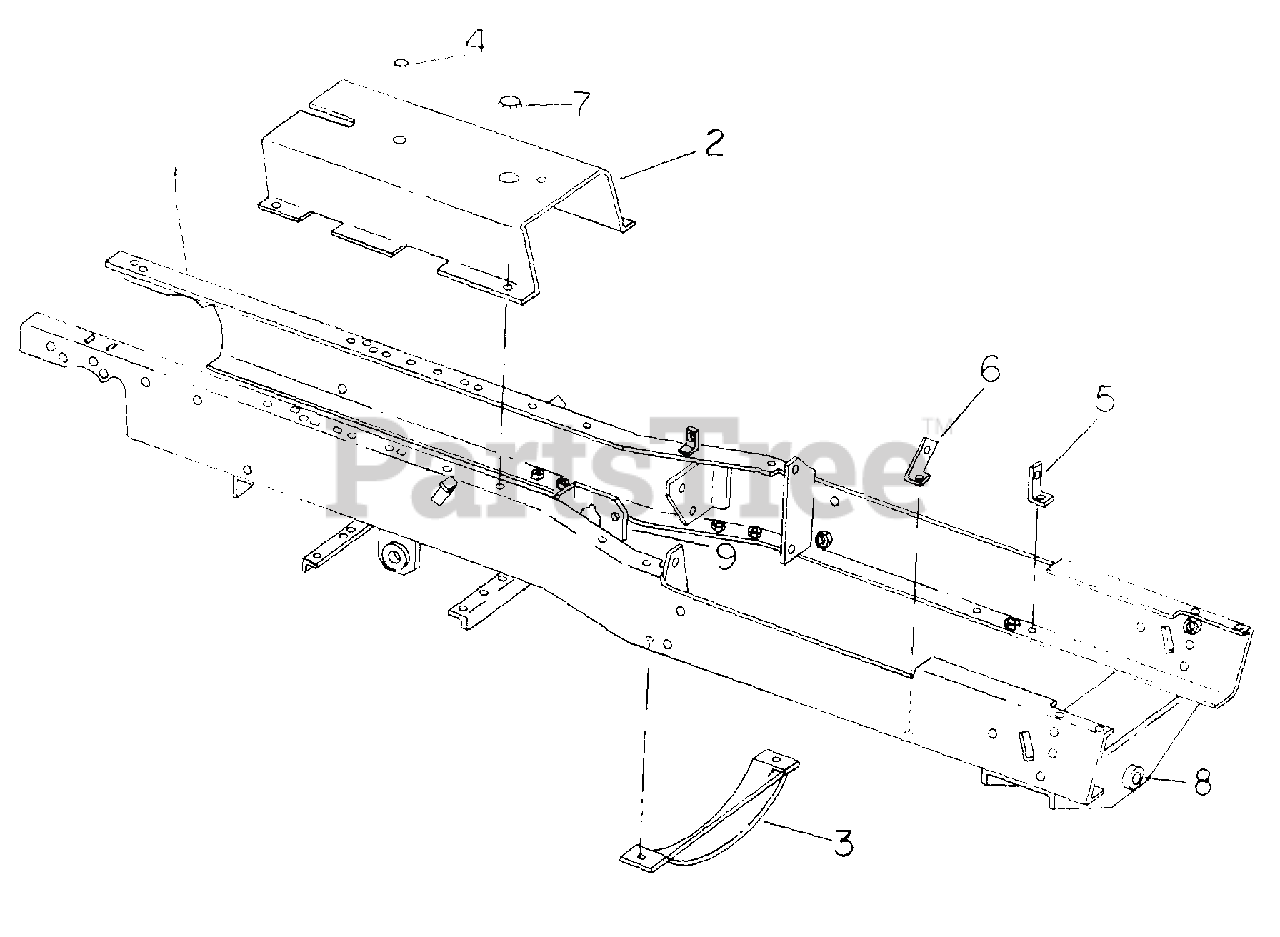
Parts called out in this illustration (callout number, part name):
2	COVER, FRAME TOP
3	SHIELD ASSY, FLYWHEEL
4	PLUG, 7/8 IN. BUTTON
5	ANGLE ASSY, ENGINE BRACKET LH
6	ANGLE ASSY, ENGINE BRACKET RH
7	PLUG, 1-1/4 IN. BUTTON
8	HUB, FRONT AXLE PIVOT PIN FRONT
8	HUB, FRONT AXLE PIVOT PIN REAR
9	SUPPORT, STEERING GEAR
